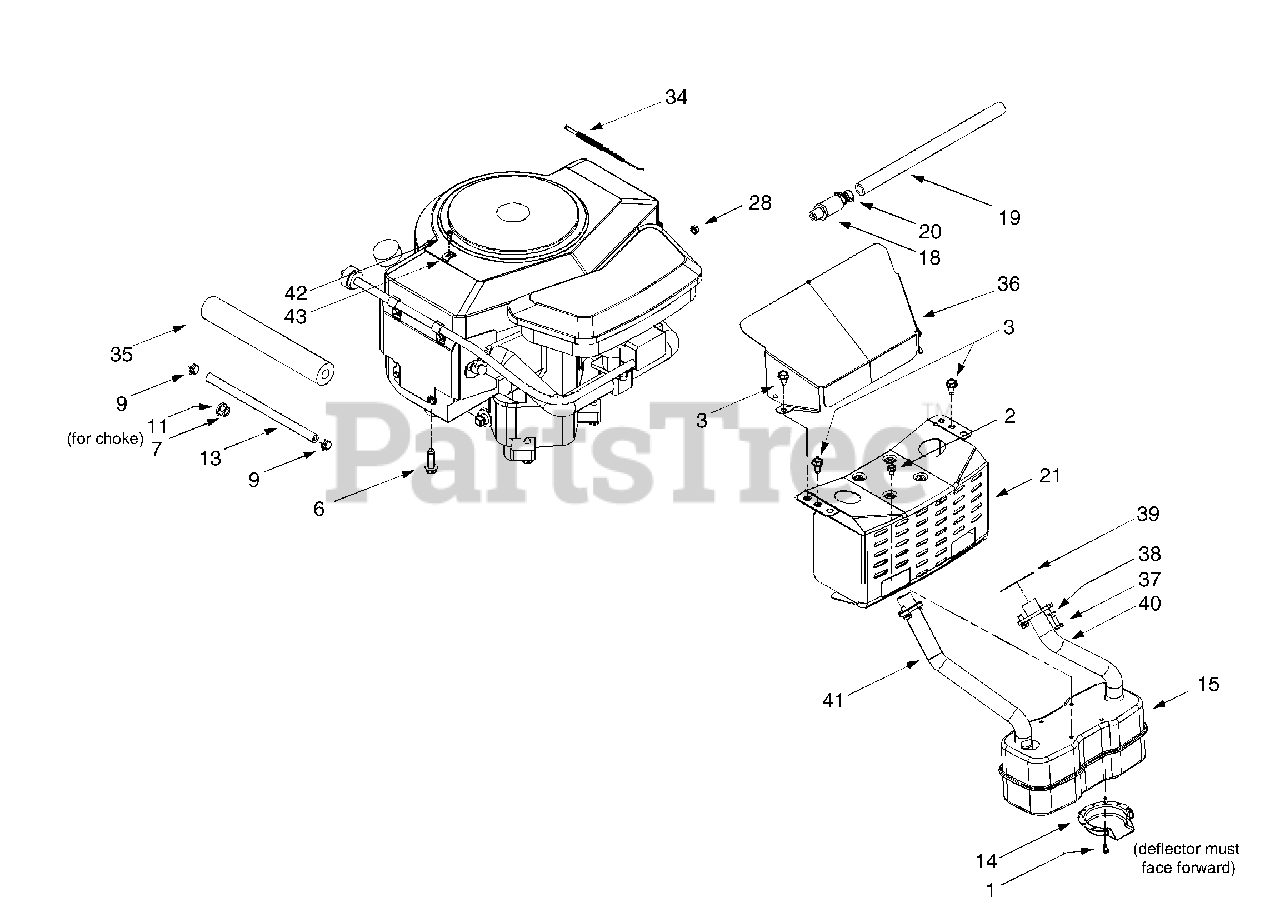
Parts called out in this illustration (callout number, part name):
1	Self-tapping Screw, #8-32 x .375
2	Self-tapping Screw, 1/4-20 x .5
3	Self-tapping Screw, 5/16-18 x .625
6	Self-tapping Screw, 3/8-16 x 1.25
7	Hex Nut, 3/8-16
9	Hose Clamp
11	Lock Washer, .406 x .875 x .059
13	Fuel Line Hose
14	Muffler Deflector
15	Muffler, Twin Inlet
18	Oil Drain Valve
19	Oil Drain Hose
20	Oil Drain Cap
28	Hex Sems Nut, 1/4-20
34	Throttle Cable (OHV V-Twin & Opposed Twin)
35	Foam, .625 x 1.5 x 10
37	Hex Cap Screw, 1/4-20 x .620 (Grade 5)
38	Lock Washer, 1/4
39	Exhaust Gasket (Opposed Twin)
40	LH Exhaust Pipe (Opposed Twin)
41	RH Exhaust Pipe (Opposed Twin)
42	Screw, #10-16 x .5
43	Clamp, 9/16
